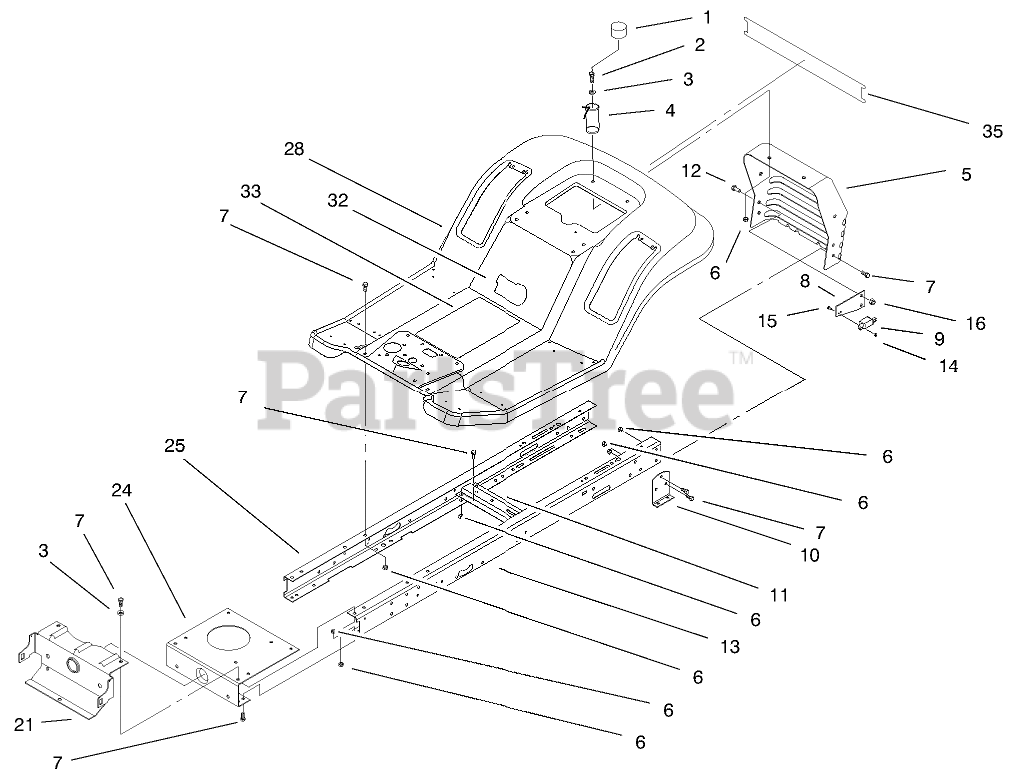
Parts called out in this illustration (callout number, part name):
1	CAP-PROTECTOR
2	SCREW-HH
3	WASHER-PLAIN
4	SPRING-COMPRESSION
5	SUPPORT-SEAT/REAR HITCH
6	NUT-LOCK, NI
7	SCREW-HH
8	PLATE-SWITCH
9	SWITCH-POLE, SINGLE
10	BRACKET-TRANSAXLE, MOUNTING
11	BRACKET-IDLER PIVOT
12	SCREW-HH
13	RAIL-FRAME, LH
14	NUT-LOCK
15	SCREW-SHH
16	NUT-LOCK, NI
21	SUPPORT-FRONT, AXLE
24	PLATE-MOUNTING, ENGINE
25	RAIL-FRAME, RH
28	REAR BODY ASM
32	Decal-USA (only on: 71223)
33	Decal-Gear Instr. Intl (only on: 71226)
33	Decal-Instruction (only on: 71223)
35	DECAL-REAR, BODY
